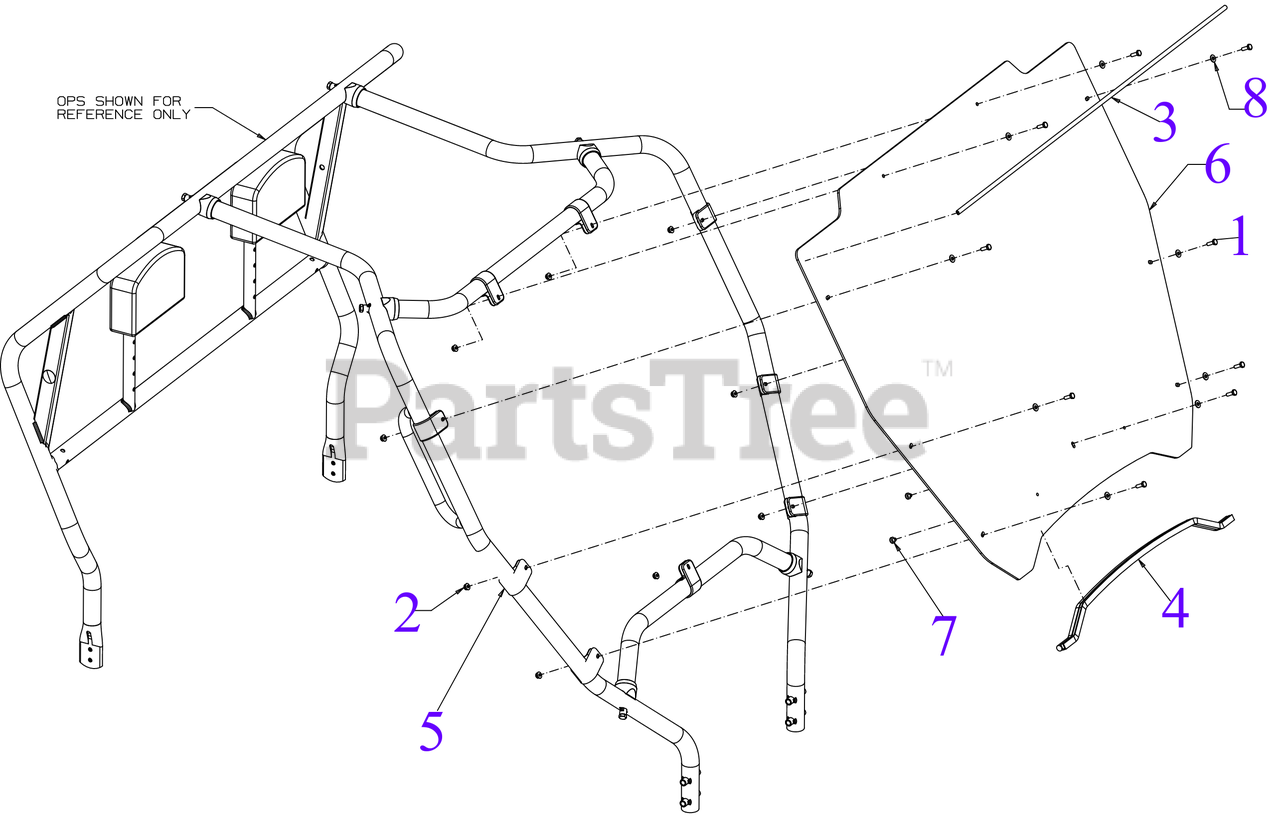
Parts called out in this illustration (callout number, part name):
1	SCREW 1/4-20X.75 GR5
2	FLANGE LOCK NUT
6	WINDSHIELD
7	BUMPER .500 x .219
8	FLAT WASHER
